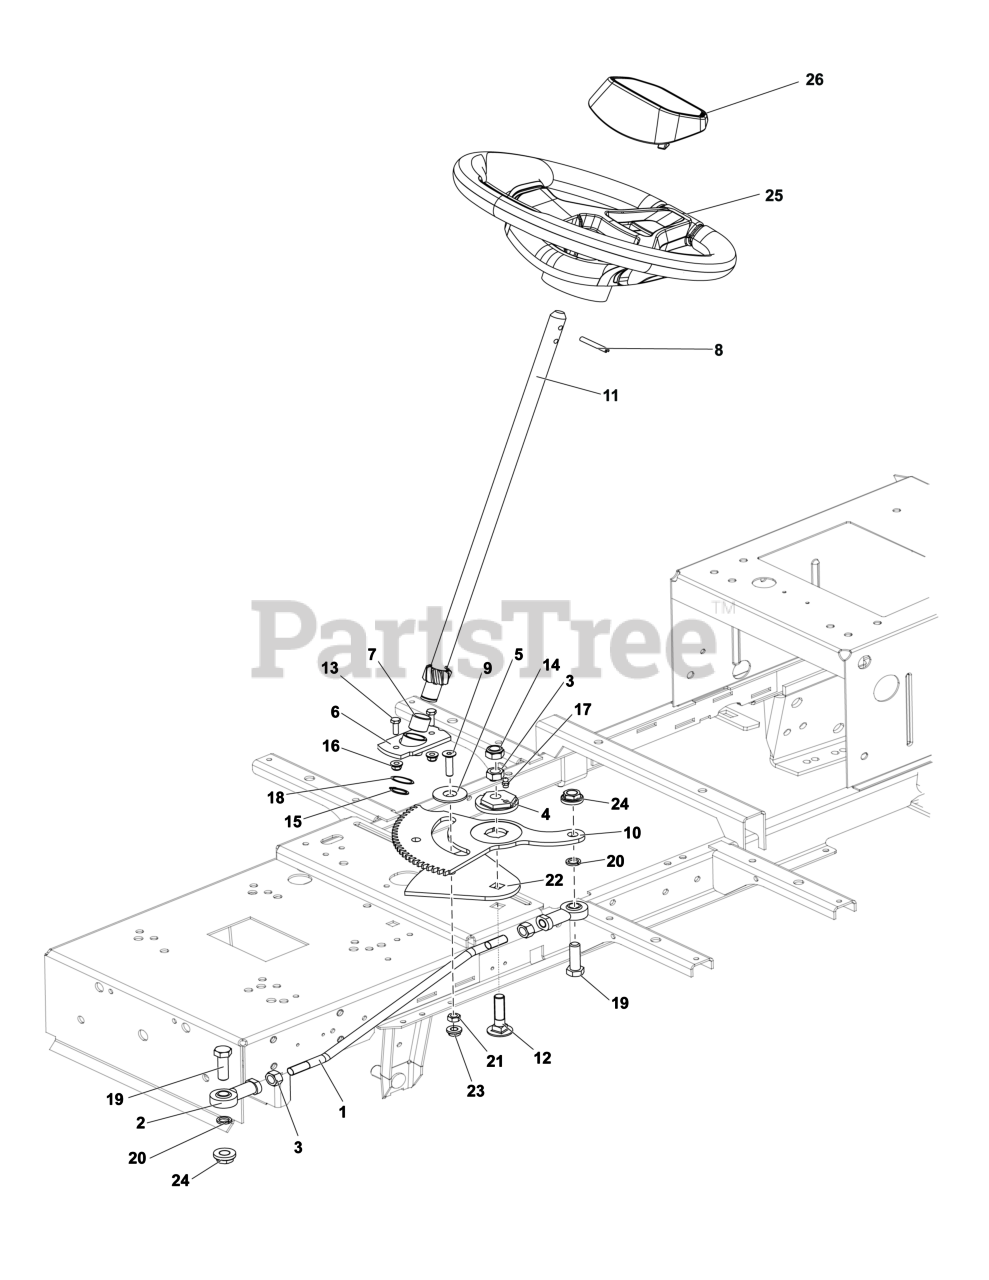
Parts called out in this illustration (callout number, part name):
2	JOINT, Ball
4	ECCENTRIC
17	ZERK, Grease Fitting
25	WHEEL, Steering
26	CAP, Steering Wheel
